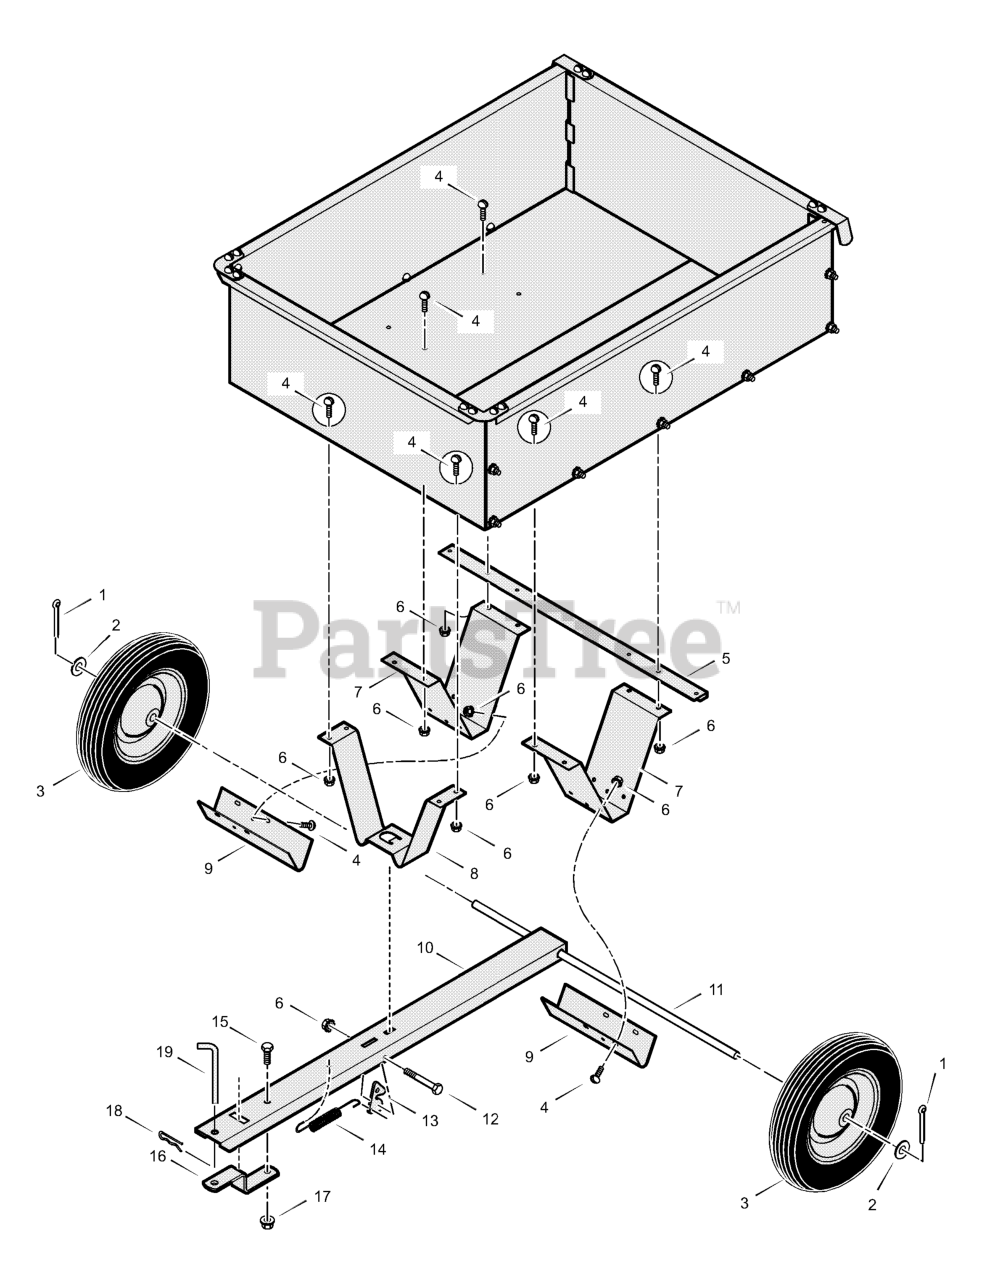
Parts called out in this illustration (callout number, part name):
1	Pin, Cotter
4	Screw 14-20x0.50
5	Support, Bottom
6	Nut, Keps 1/4-20
7	Support, Axle
8	Support, Tongue
9	Retainer, Axle
10	Tongue (Black)
12	Bolt, Hex 1/4-20x3.25
15	Bolt, Hex 3/8-16x0.75
17	Nut, Lock 3/8-16
18	Pin, Hair
19	Pin, Drawbar
